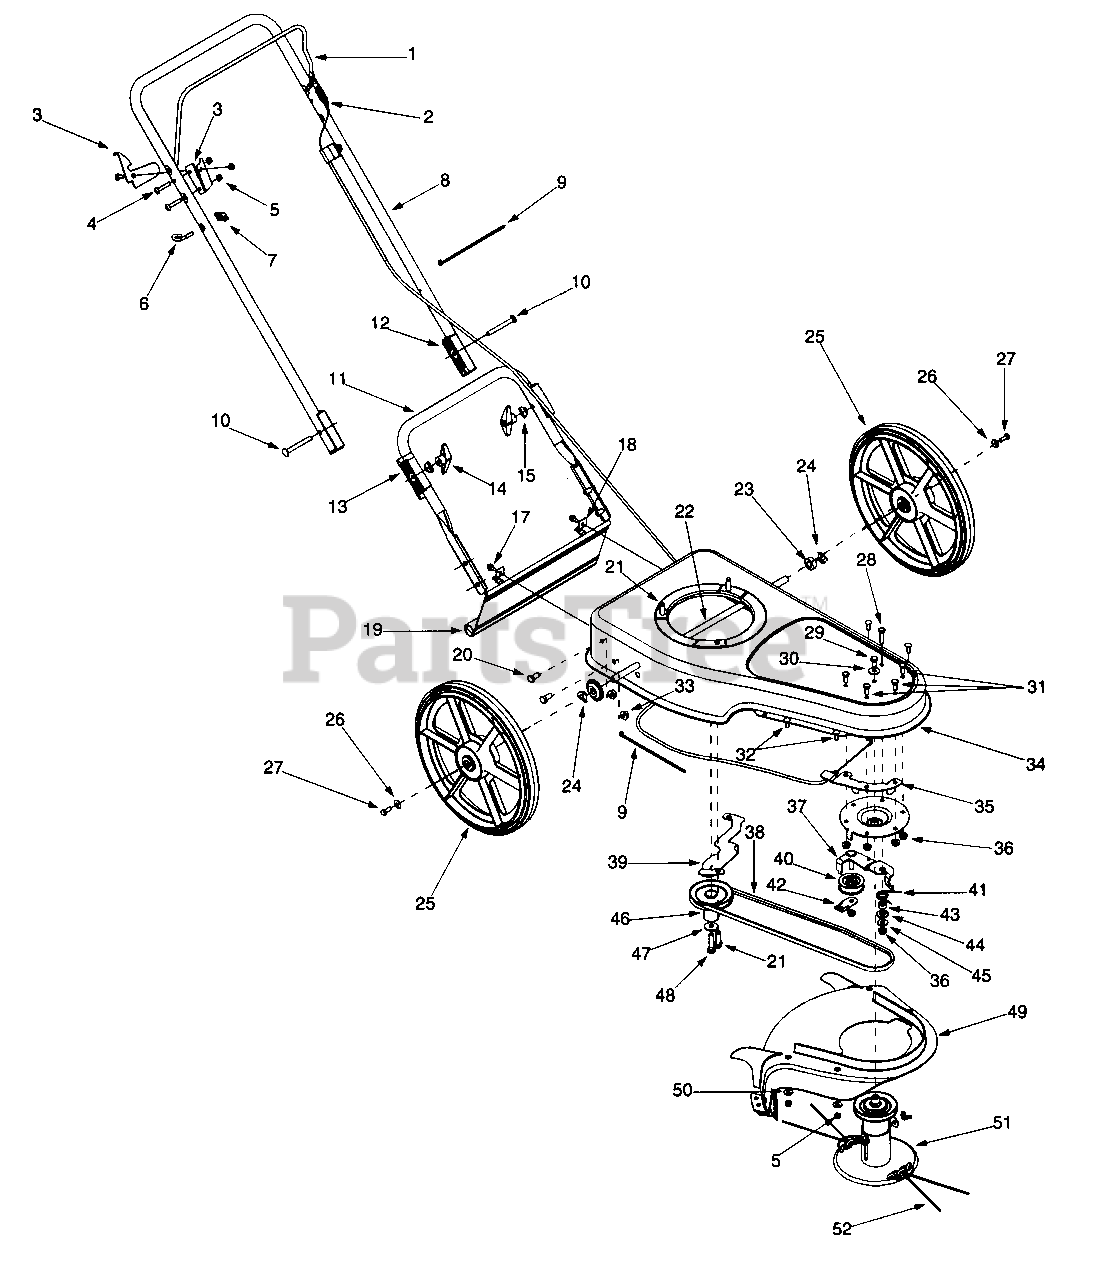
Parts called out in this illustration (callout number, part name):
2	Clutch Cable
3	Control Lock Bracket
4	Machine Screw 1/4-20 x 1.50
5	Hex Lock Nut 1/4-20
6	Eye Bolt 1/4-20
7	Wing Nut
10	Carriage Screw 5/16-18 x 3.0
13	Lower Handle Connector
14	Wing Nut
15	Shoulder Washer.320 ID x .93
17	Hex Wash. Screw 1/4-14 x .625
18	Trail Shield Clip
19	Trail Shield
20	Hex Cap Screw 3/8-16 x .750
21	Hex Wash. Screw 3/8-16 x 1.25
22	Trimmer Axle
23	Spacer .51 ID x 1.0 OD
24	Spacer Washer .501 ID x 1.0
25	Wheel Assembly
26	Bell Washer .265 ID x .75 OD
27	Hex Cap Screw 1/4-20 x .75
28	Screw 5/16-18 x 1.25
29	Hex Cap Screw 5/16-24 x .625
30	Bell Washer .325 ID x .930 OD
31	Screw 5/16-18 x .75
32	Hex Carriage Screw 1/4-20 x .75
33	Flange Lock Nut 3/8-16
36	Flange Lock Nut 5/16-18
37	Idler Bracket Assembly
38	V-Belt
41	Torsion Spring
43	Idler Spacer
44	Idler Spacer
45	Flat Washer
46	Engine Pulley
47	Bell Washer .396 ID x 1.14 OD
48	Hex Cap Screw 3/8-24 x 1.50
49	Trimmer Deflector Assembly
50	Flat Washer .28 ID x .74 OD
51	Spindle Assembly
52	Trimmer Line .130 Dia
